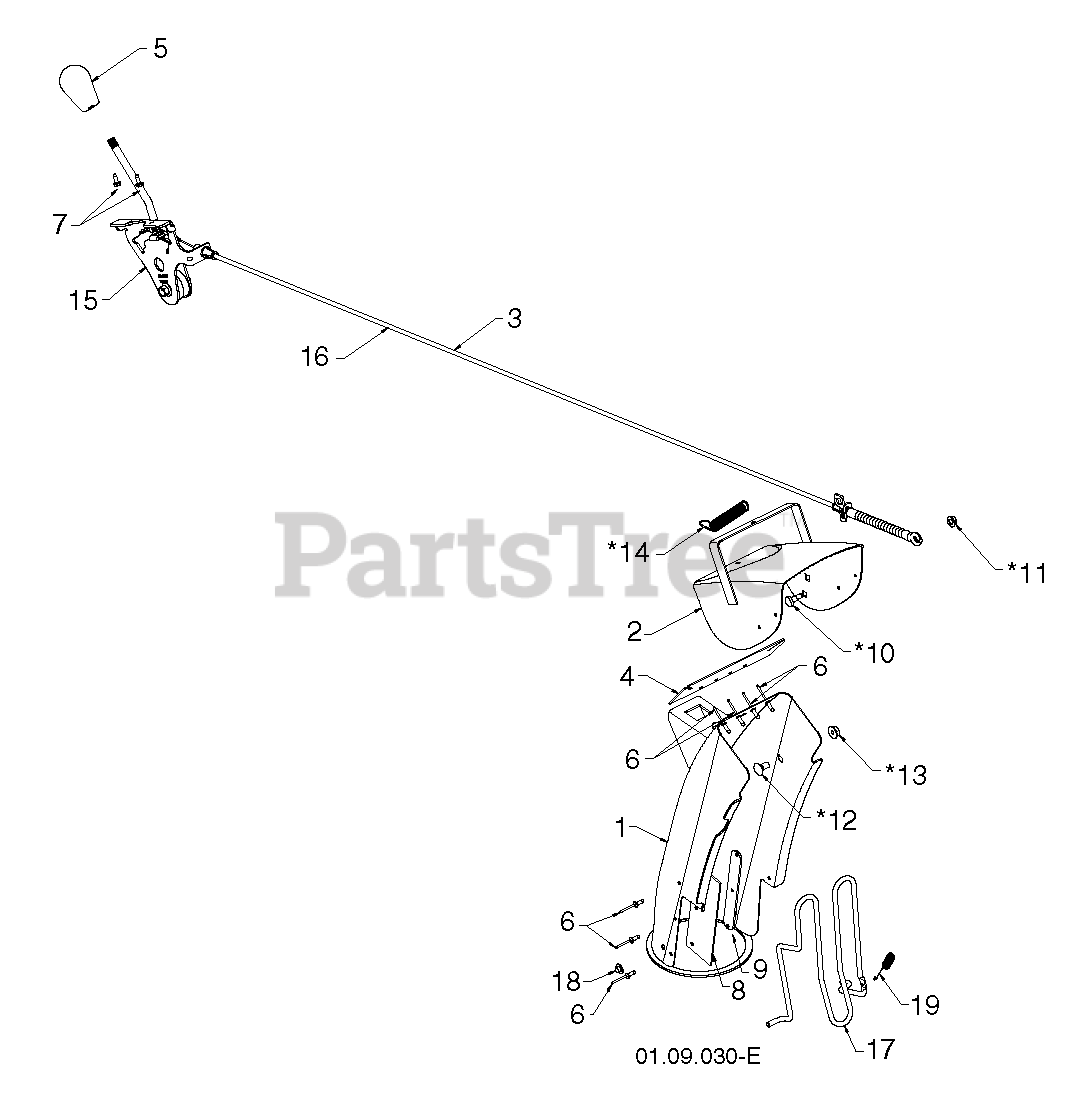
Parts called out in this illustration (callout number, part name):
1	RP_CHUTE.WELDMENT.SNOW.ORANGE
2	DEFLECTOR.WELDMENT.PNT.ORANGE
3	CONTROL.ASM.DEFLEC.BLK.BOWDEN
4	SEAL.DEFLECTOR
5	KNOB.OVERMOLD.DS.HUSQVARNA/BLK
6	RIVET BLIND
8	SHIELD.SNOW.CHUTE
9	STRAP.SHEILD.RETAINER
10	BOLT, SHOULDER
11	NUT.HEX.FLANGE.1/4
12	BOLT
13	NUT.LOCK.5/16-18
14	SPRING.DEFLECTOR.REM.CHUTE
15	RP CNTRL.HEAD.ASSEM.DEFLECTOR
16	RP CABLE.DEFLECTOR.BOWDEN
17	ROD.GUARD.CHUTE (2 2)
18	NUT
19	SPRING.CHUTE.GUARD
